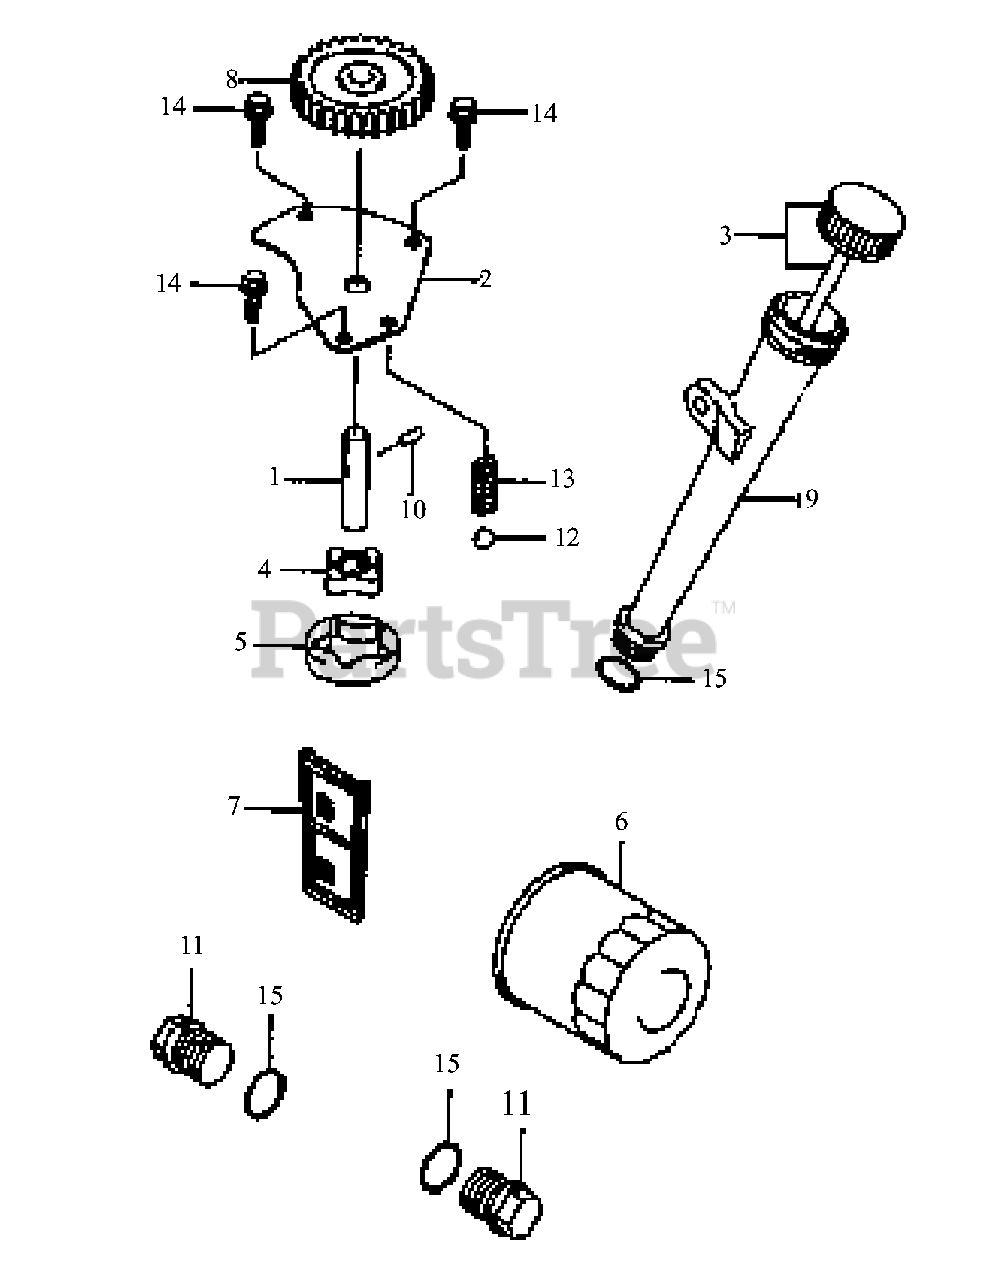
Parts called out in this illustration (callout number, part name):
1	Shaft, Oil Pump
4	Rotor-Pump In
5	Rotor-Pump Out
6	Filter-Oil
7	Filter-Oil Screen
8	Gear-Spur
10	Pin
11	Plug
